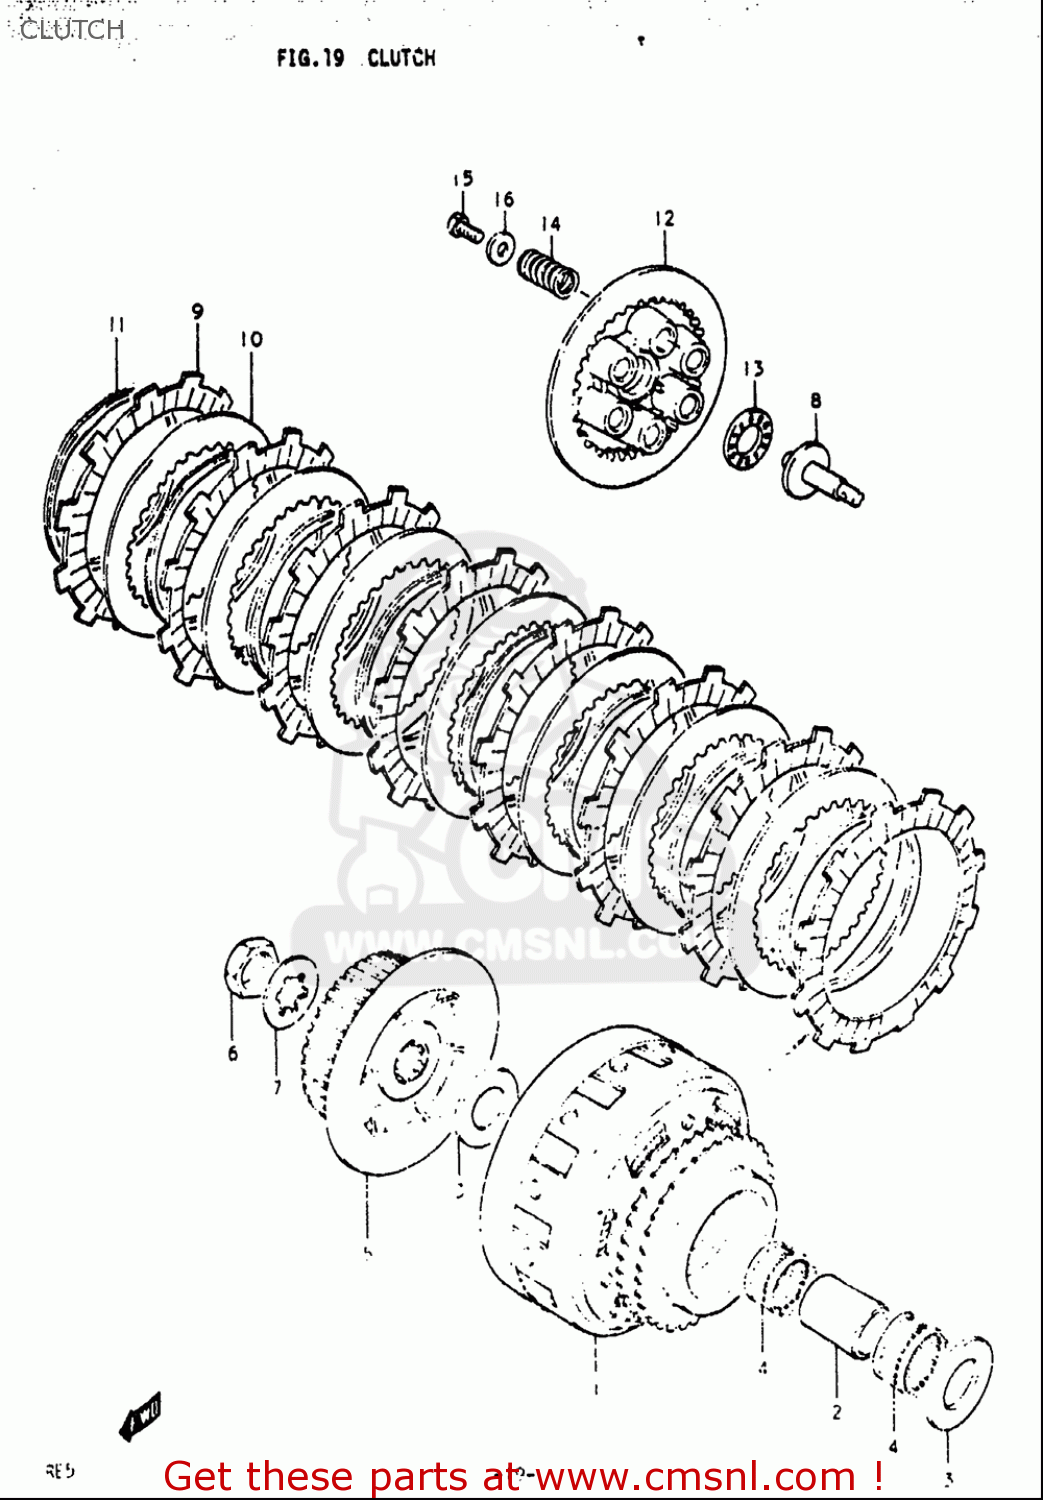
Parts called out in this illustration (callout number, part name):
6	NUT
7	WASHER,LOCK
9	PLATE,CLUTCH DRIVE (NAS)
10	PLATE,CLUTCH DRIVEN (NAS)
11	V RING
13	BEARING(20.1X35X2.8)
14	SPRING
15	BOLT
16	WASHER(6.5X20X1.6)
